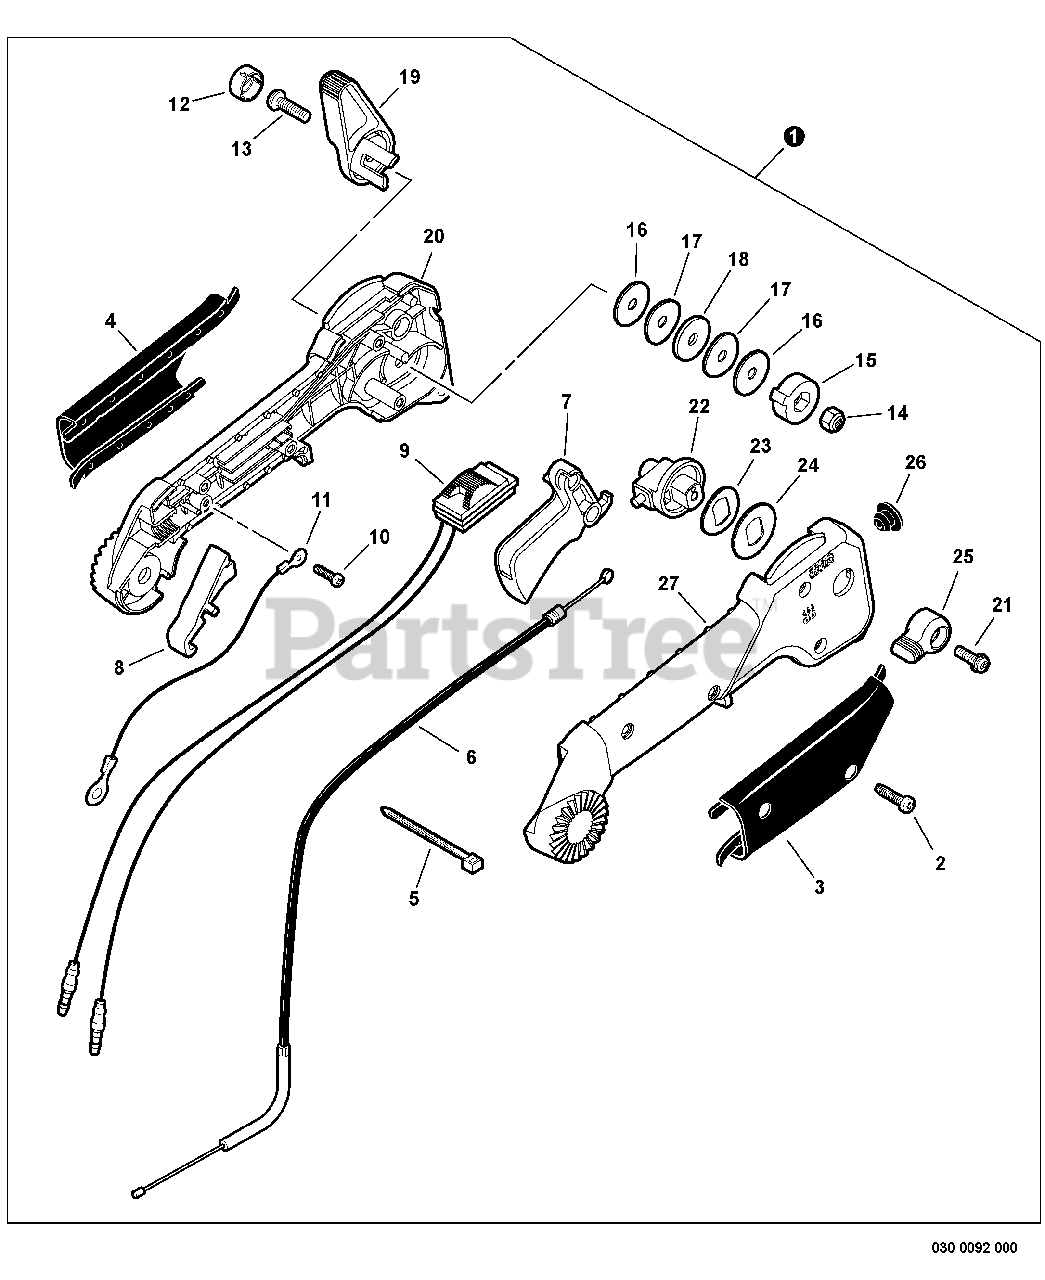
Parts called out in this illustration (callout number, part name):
1	CONTROL HANDLE ASSY
2	SCREW - 4
3	GRIP, HANDLE - RIGHT
4	GRIP, HANDLE - LEFT
5	TIE, CABLE
6	CABLE, THROTTLE
7	TRIGGER, THROTTLE
8	COVER, HANDLE
9	SWITCH, IGNITION
10	SCREW - 3
11	LEAD - GROUND
13	SCREW - 6
14	NUT - 6 -- NYLON
15	LEVER, THROTTLE
16	WASHER - 6
17	WASHER - SPRING
18	WASHER - 6
19	LEVER, THROTTLE CONTROL
20	HANDLE, CONTROL - LEFT
21	SCREW - 4
22	THROTTLE LIMITER ASSY
23	WASHER - SPRING
25	LEVER, THROTTLE LIMITER
27	HANDLE, CONTROL - RIGHT
